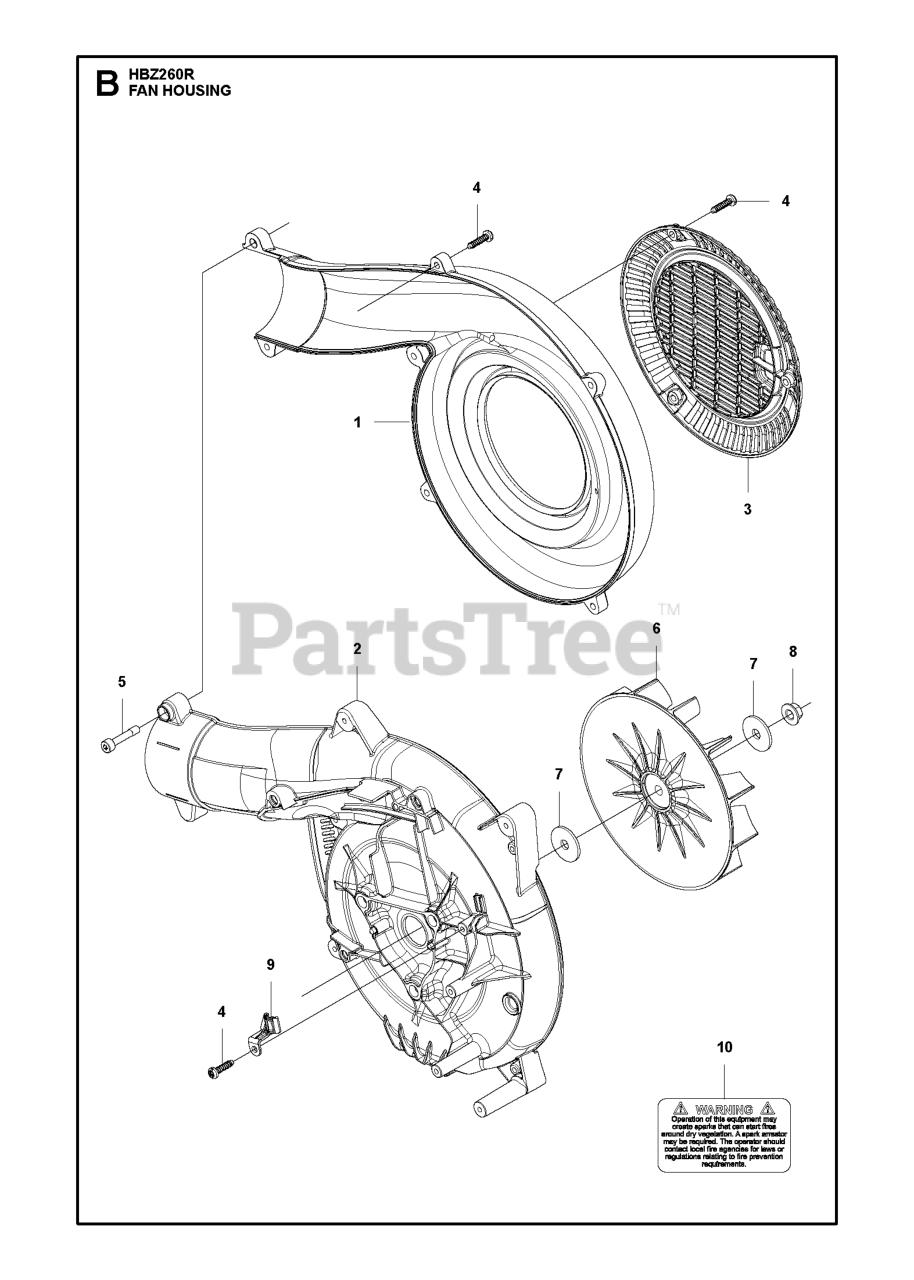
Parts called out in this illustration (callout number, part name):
1	VOLUTE COVER
2	VOLUTE CASE
4	SCREW, TORX (RPLS T4970-52001)
5	BOLT M6X1 CAPTIVE
10	LABEL SPARK WARNING
